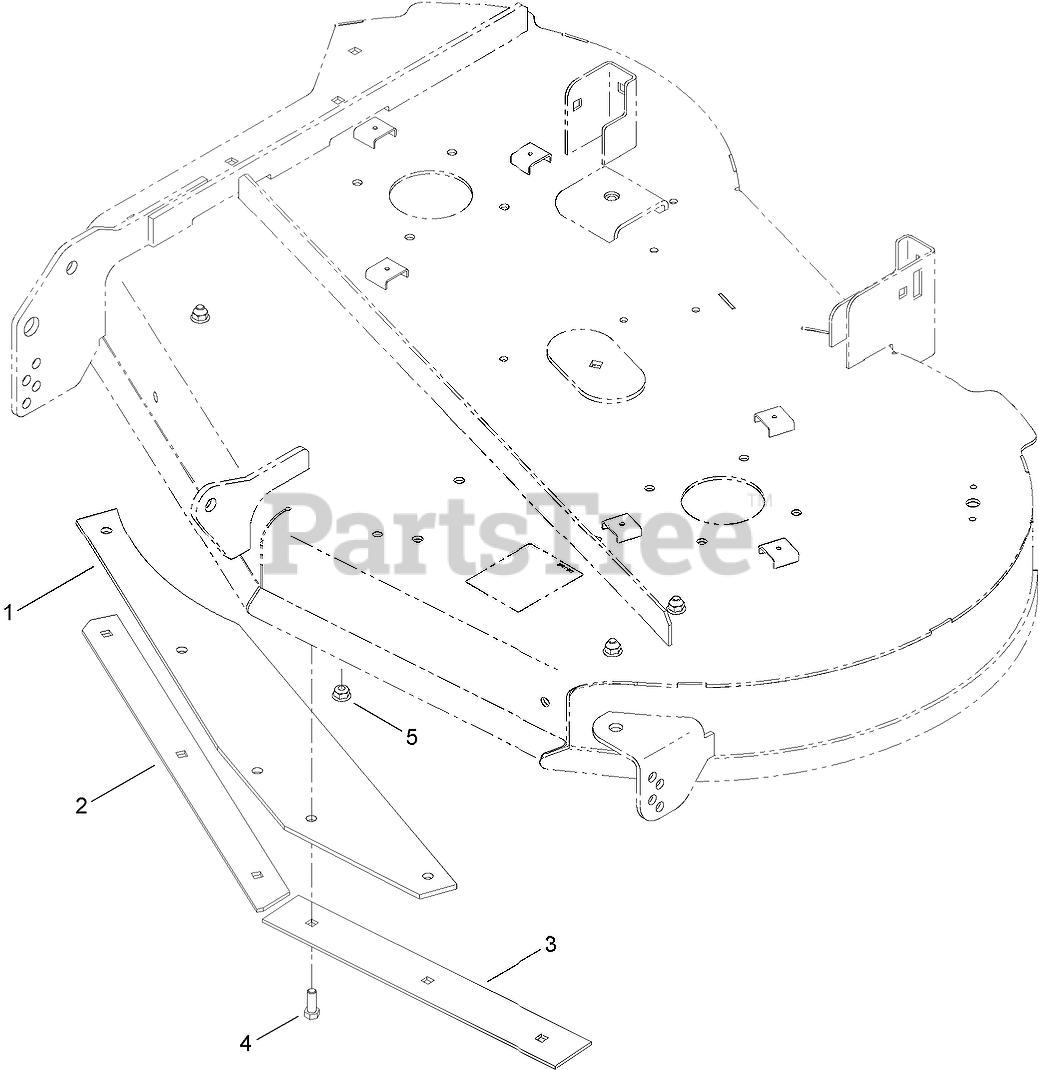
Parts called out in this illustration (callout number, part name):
1	SKIRT-RUBBER
2	PLATE-RH
3	PLATE-LH
4	SCREW-HH
5	NUT-HF, NI
